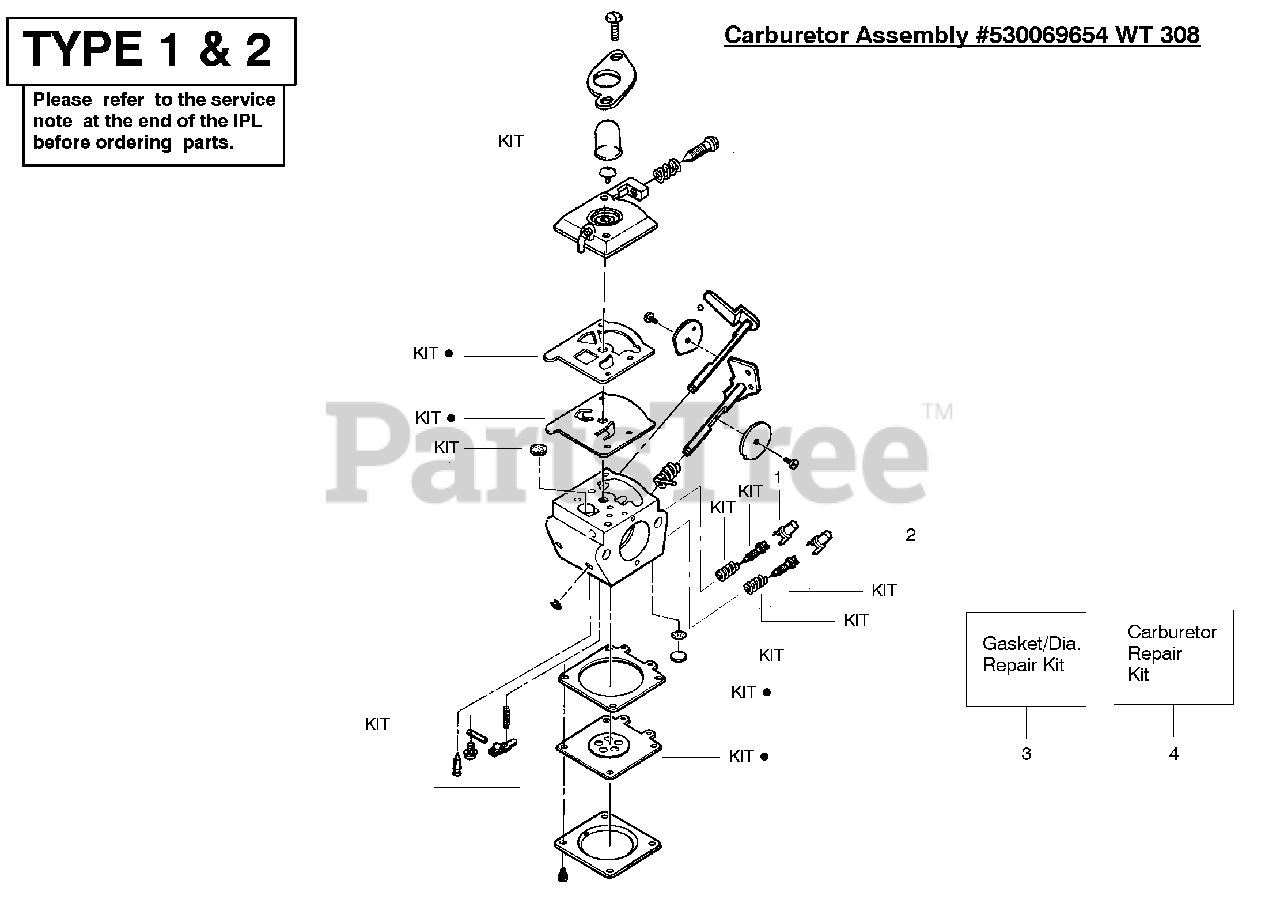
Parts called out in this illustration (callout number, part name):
1	Limiter Cap-Low (tan)
2	Limiter Cap-High (brown)
3	Gasket/Diaphragm Kit
4	Carburetor Repair Kit
